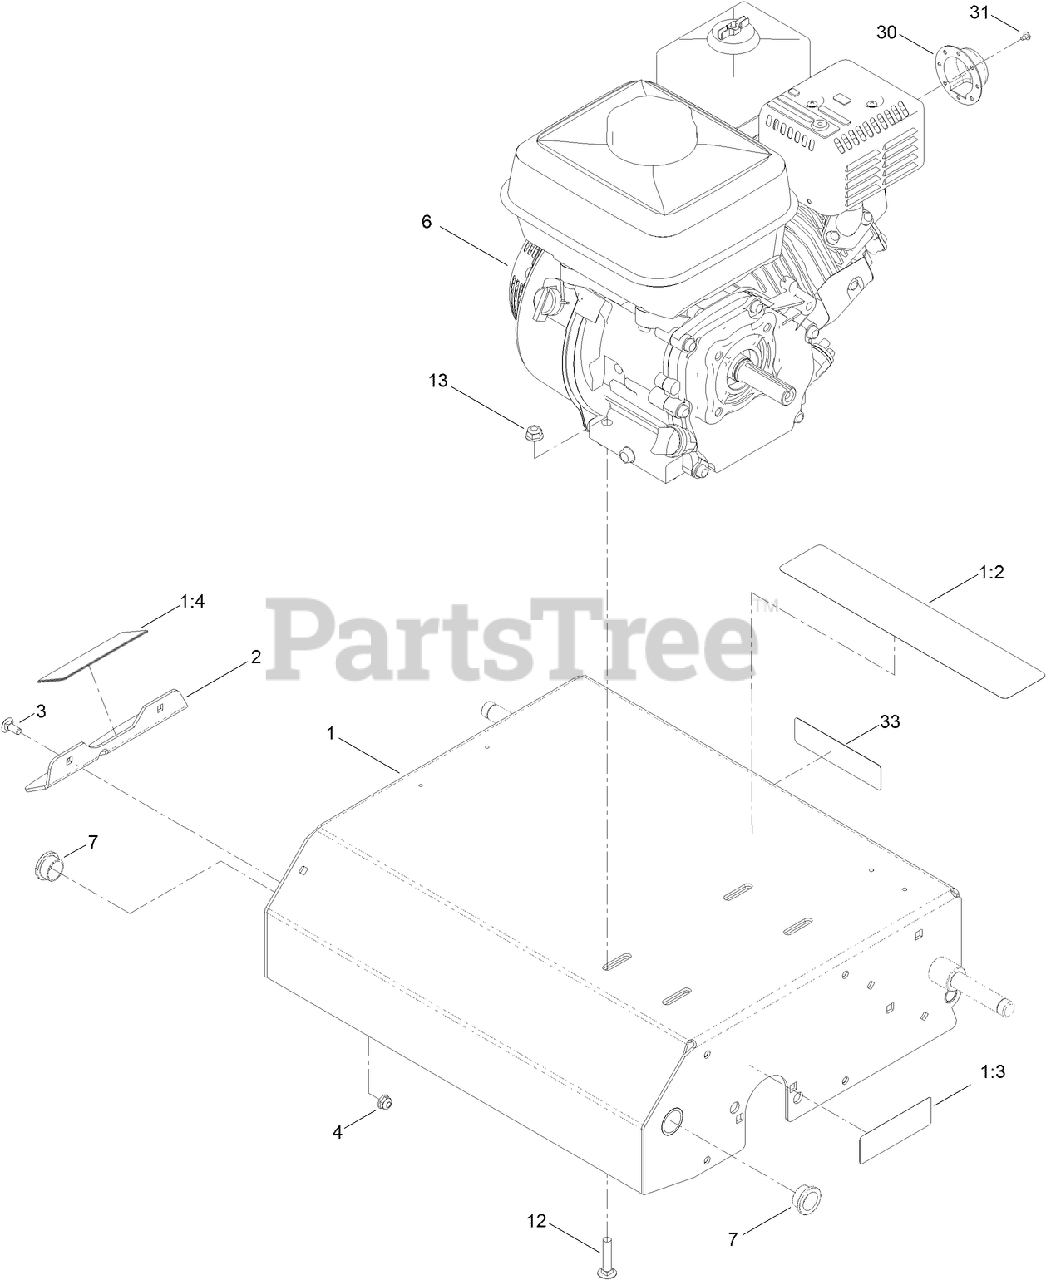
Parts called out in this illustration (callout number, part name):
1	FRAME ASM
1:2	DECAL-WARNING
1:3	DECAL-WARNING, SHIELDS
1:4	DECAL-DANGER
2	GUARD-HAND
3	SCREW-CARR
4	NUT-HF
7	BUSHING
12	BOLT-CARR
13	NUT-HF, NI
30	DEFLECTOR
31	SCREW-PPHTF
33	DECAL-ARRESTER, SPARK
